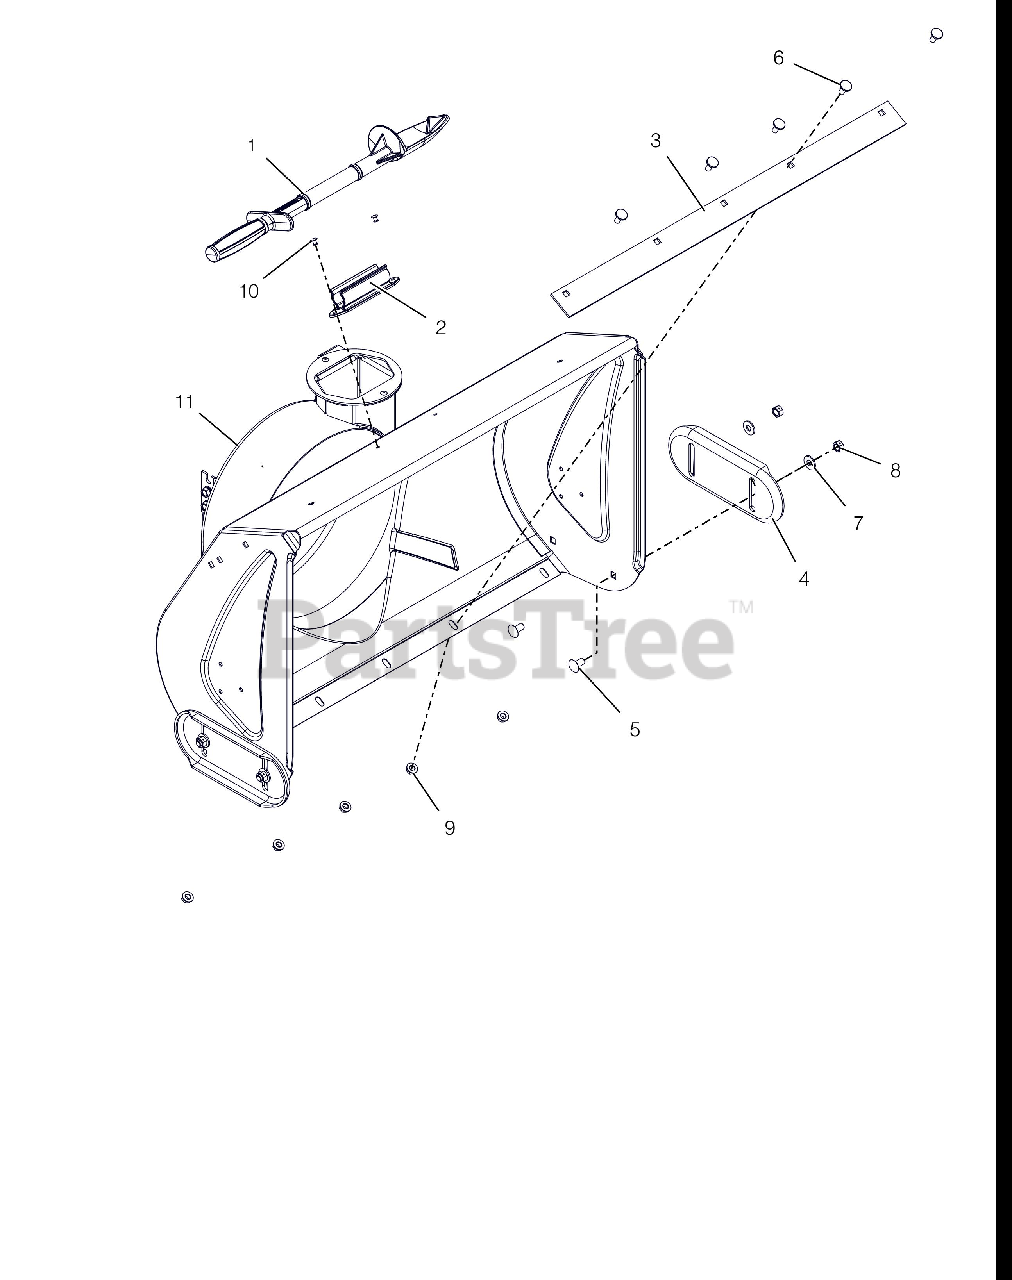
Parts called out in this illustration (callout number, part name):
1	DEVICE, SNOW CLEAN OUT
2	MOUNT, SNOW CLEAN OUT
3	SCRAPER BLADE, 28" COMPACT HI
4	SKID SHOE, REVERSIBLE
5	@BLT-RHDSSQNK .38-16X.75 G5YZ
6	BOLT, MODIFIED HEAD CARRIAGE
7	@WSHR-FL-STL.38X.875X.083 YWZC
8	@NUT-LK-CTR .38-16 YWZC
9	@NUT-LK-TOP-FLG .31-18 YWZC
10	RVT-POP .187 YZ
11	BLOWER HOUSING, 28"
